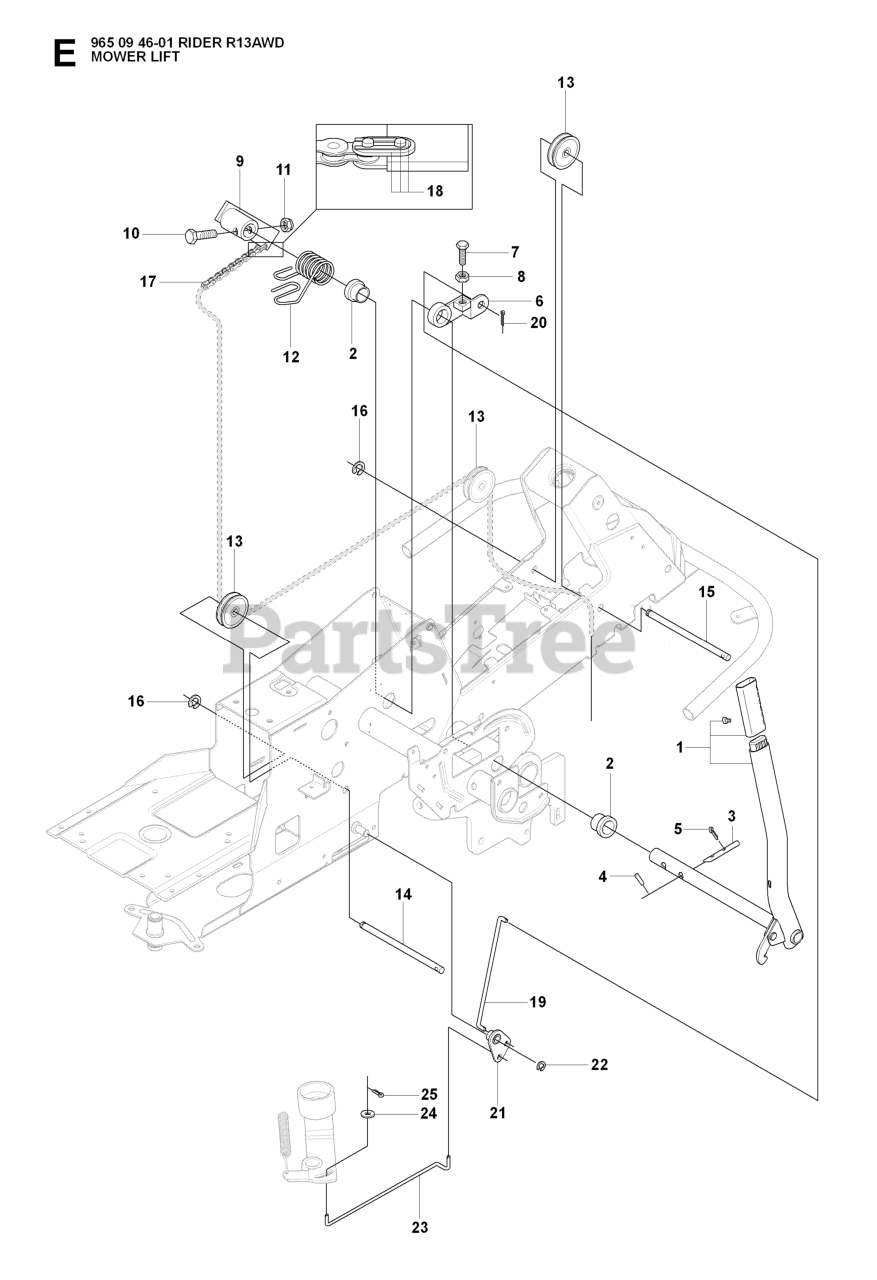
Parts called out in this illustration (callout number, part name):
1	LIFTING LEVER ASSY
2	BEARING FLANGE
3	RP PIN
6	LEVER CLUTCH
8	NUT
9	LIFTING ARM
19	CONNECTION ROD
22	RETAINING RING
23	CONNECTION ROD
